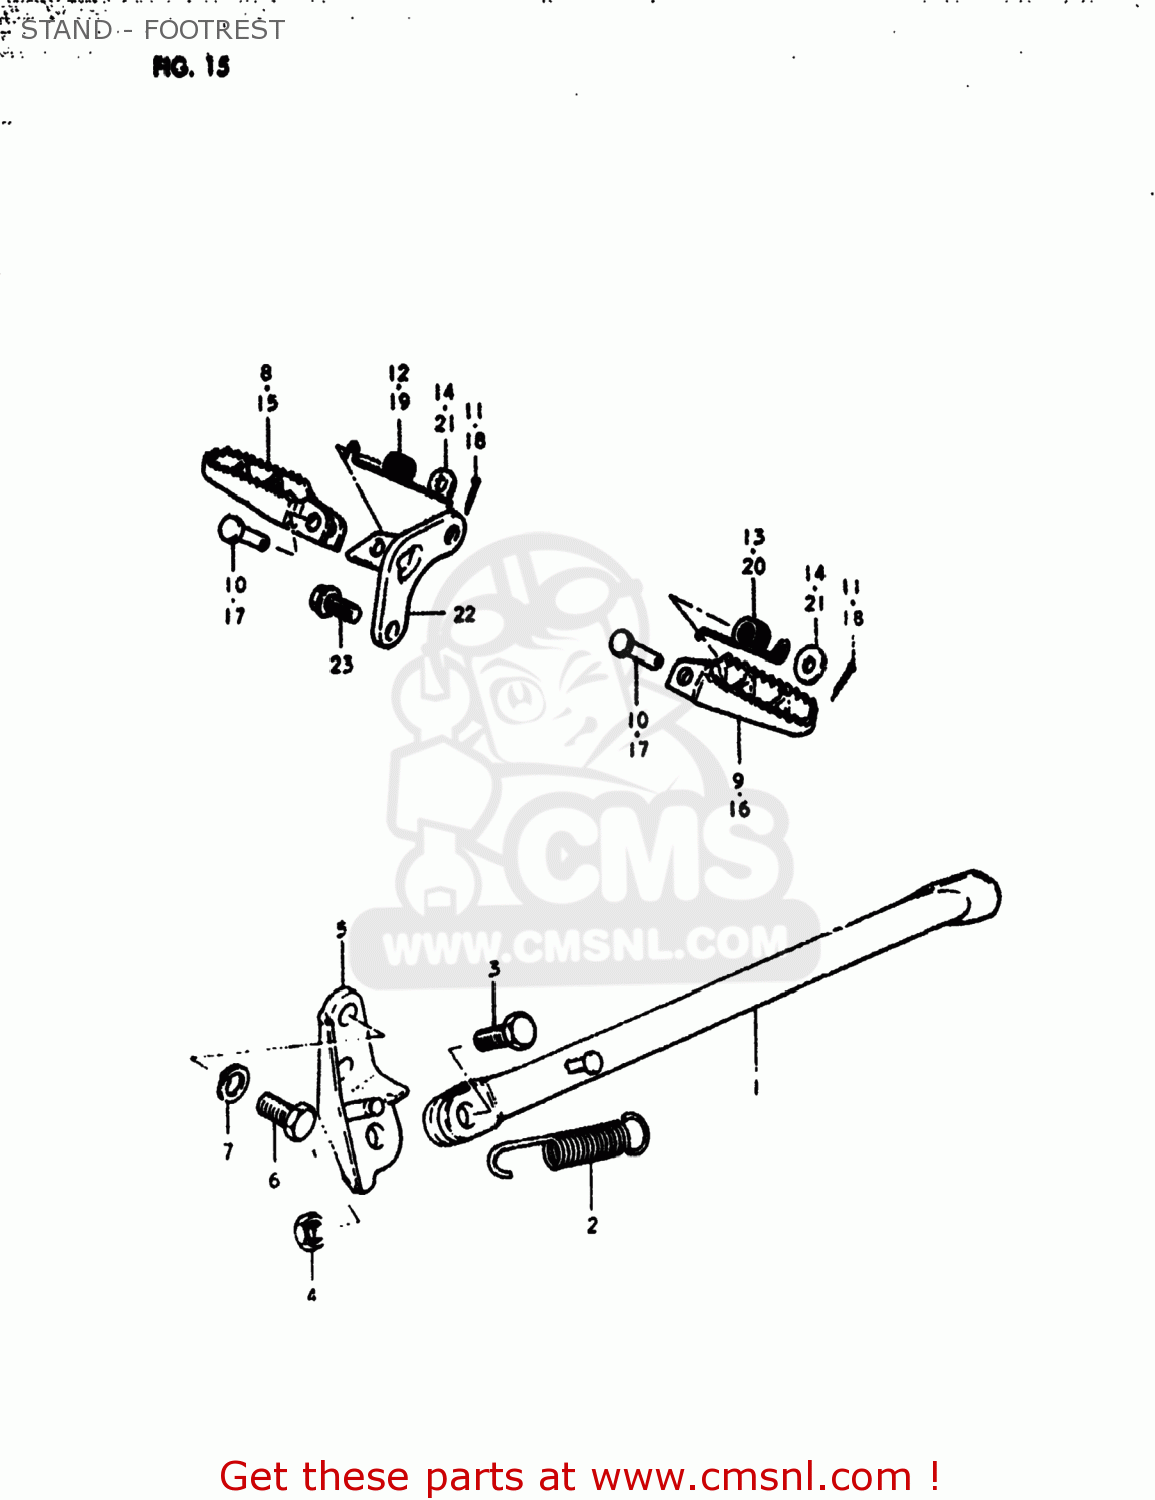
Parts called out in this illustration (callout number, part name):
1	STAND,SIDE
2	SPRING
3	BOLT(10X30)
4	NUT
5	BRACKET,PROP STAND
6	BOLT(10X19)
7	LOCK WASHER
8	RUBBER,FOOTREST
9	FOOTREST
10	PIN
11	PIN 20X20
12	SPRING
13	SPRING
14	WASHER
15	RUBBER,FRONT FOOTREST
16	FOOTREST
17	PIN
18	PIN 30X20
19	SPRING
20	SPRING
21	WASHER
22	HOLDER,FRONT FOOTREST,RIGHT
23	BOLT(10X20)
